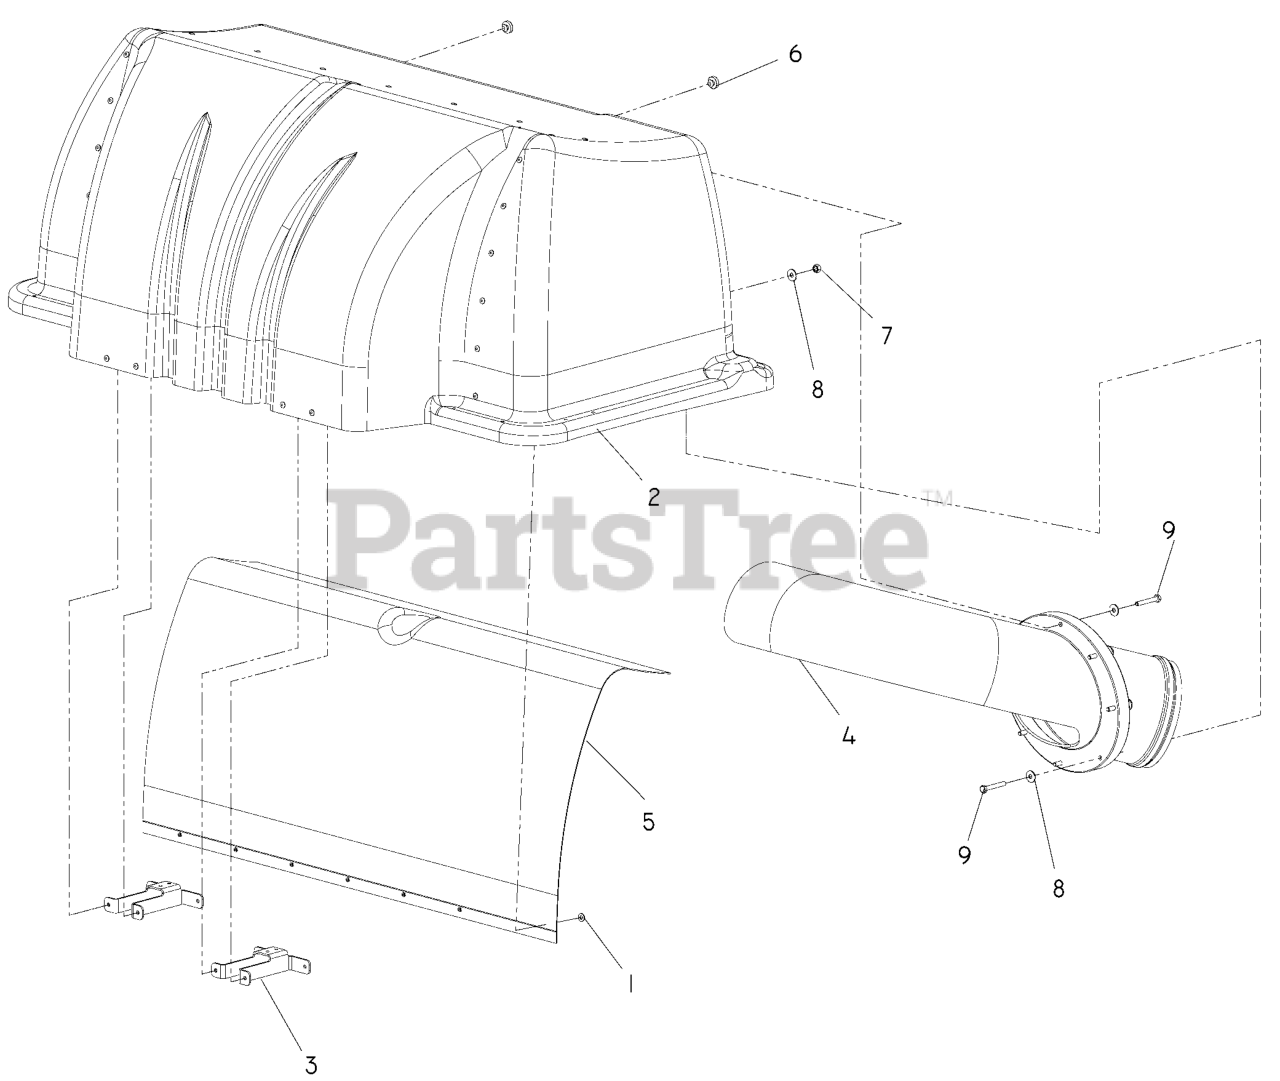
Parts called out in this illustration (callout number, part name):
1	WASHER #10
3	SUPPORT, DRAW LATCH
5	MESH, POLY DIAMOND
6	GROMMET, BUMPER
7	NUT.1/4-20.HEX.NYLOC.ZD
8	WASHER 1/4 FLAT
9	BOLT 1/4C X 1 3/4
